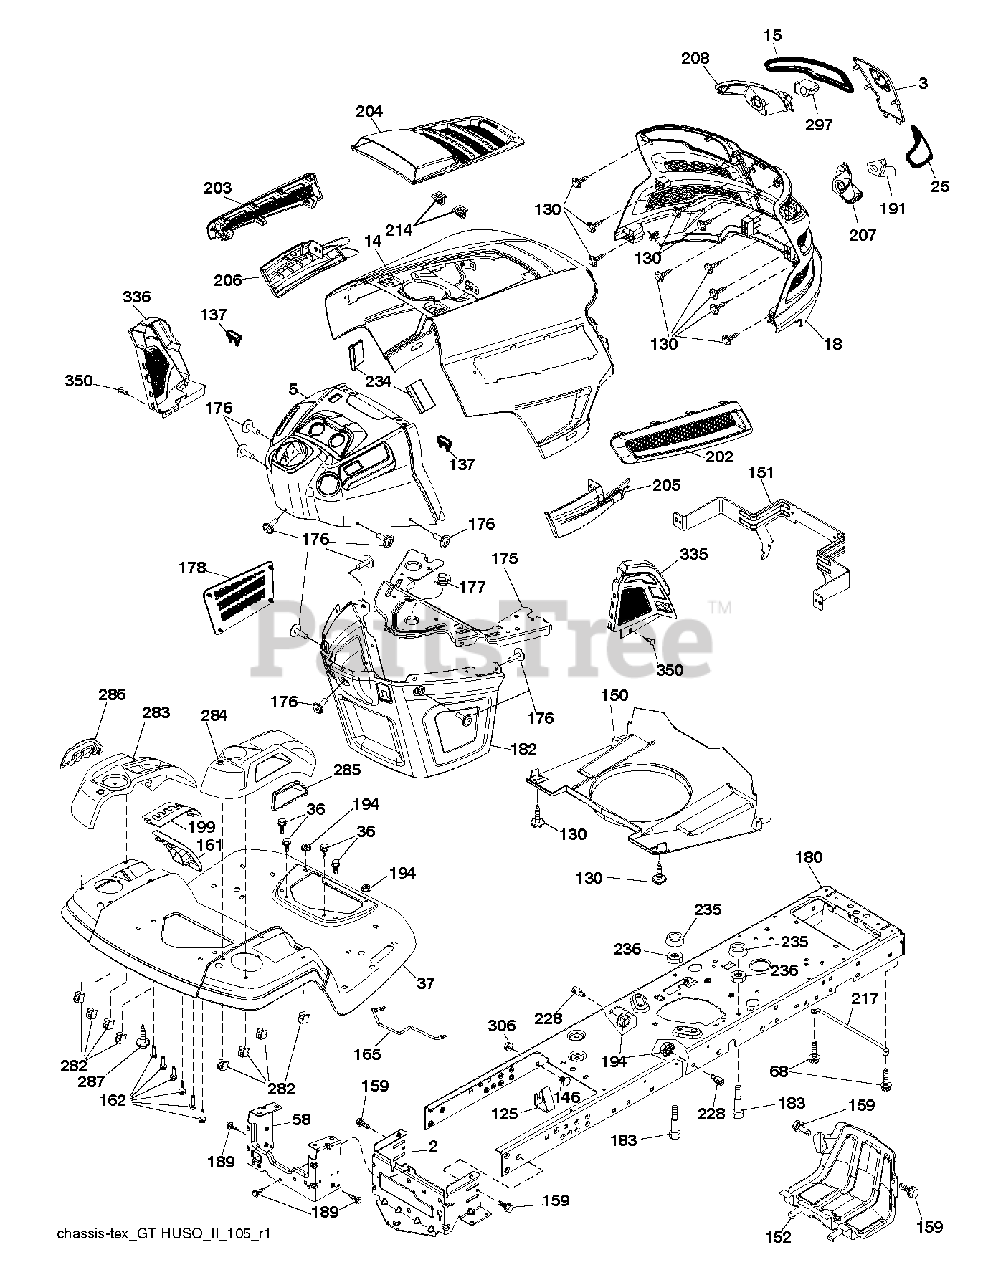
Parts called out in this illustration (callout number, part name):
2	DRAWBAR.LOWER.2PC.18/22
3	APPLIQUE.SUBASM.GT.HUSQ.II
5	DASH.UPP.GT2.DUAL.RD.PTO.MCHOK
14	HOOD.ASM.HUSQVARNA.GT.TEX.ORAN
15	LENS.HEADLIGHT.LH.GTII.2011
18	GRILLE.SUBSTRATE.2011.
25	LENS.HEADLIGHT.RH.GTII.2011
36	SCREW 5/16"
37	FENDER.TLT.FS.W/CPH/FW/RSF.668
58	DRAWBAR UPPER 2PC SMALL FENDER
68	SCREW LT
125	CLIP.FUEL.LINE
130	SCREW.#10 X 0.750.BOS
137	BUMPER DASH
146	BOLT.RDHD.SHT.SQNK.3/8-16X5/8
150	AIR.DUCT.GTV.BLACK
151	BRACKET.PIVOT.HOOD.GT.HUSQ.II
152	SHIELD.BROWNING.PNT.GT.V2
159	SCREW, 3/8-16X3/4
161	WINDOW.FUEL.LT.HUSQ.TEX.498
162	SCREW.HI-LO.CONSOLE
165	SUPPORT.TANK.REAR.B/TE
175	PLATE.CROSSMEMBER.HUSQ
176	SCREW.#10-24X5/8.RN.QU
177	BUSHING, STEERING
178	CARGO.ASM.NET.TXGT.W/C
180	CHASSIS.TEX.BOLTED
182	DASH.LOWER.COMMON.12V.ADAPTOR
183	BOLT.5/16-18X1-1/4 FULL THD
189	SCREW
191	INSERT.REFLECTIVE.RH.HUSQ.GTII
194	NUT LOCK HEX FLANGE 5/16-18
199	PLATE.DECK.LIFT.HUSQ.LT
202	VENT.SIDE.RH.GT.HUSQ.II.
203	VENT.SIDE.LH.GT.HUSQ.II.498
204	VENT.TOP.HUSQ.GT2
205	SIDE.TRIM.RH.GT.HUSQ.II
206	SIDE.TRIM.LH.GT.HUSQ.II.GRAY
207	BEZEL LIGHT.RH.GT.II.MYLAR
208	BEZEL LIGHT.LH.GT.II.MYLAR
214	CLIP.RETAINER.TINNER.
217	ROD.PIVOT.HOOD
228	STUD.FASTNER.W/ANTI-ROTATE
234	BUMPER.HOOD.TEX.HUSQVARNA
235	SPACER FENDER
236	NUT.CENTERLOCK.5/16-
282	CLIP.RETAINER.CONSOLE.LT.HUSQ
283	CONSOLE.DECK.LIFT.R.SDFL.HUSQ
284	CONCOLE.CNTRL.PDL.HUSQ.LT.498
285	CONSOLE INSERT RH
286	CONSOLE.INSRT.LH.HUSQ.LT.BLACK
287	SCREW 1/4X20
297	INSERT.REFLECTIVE.LH.HUSQ.GTII
306	NUT LOCK FLG 3/8-16 UNC
335	COVER.LOWER.DASH.RH.BLACK
336	COVER-LH.LOWER.DASH.GT2.BLACK
350	CLIP.X-MAS.TREE
